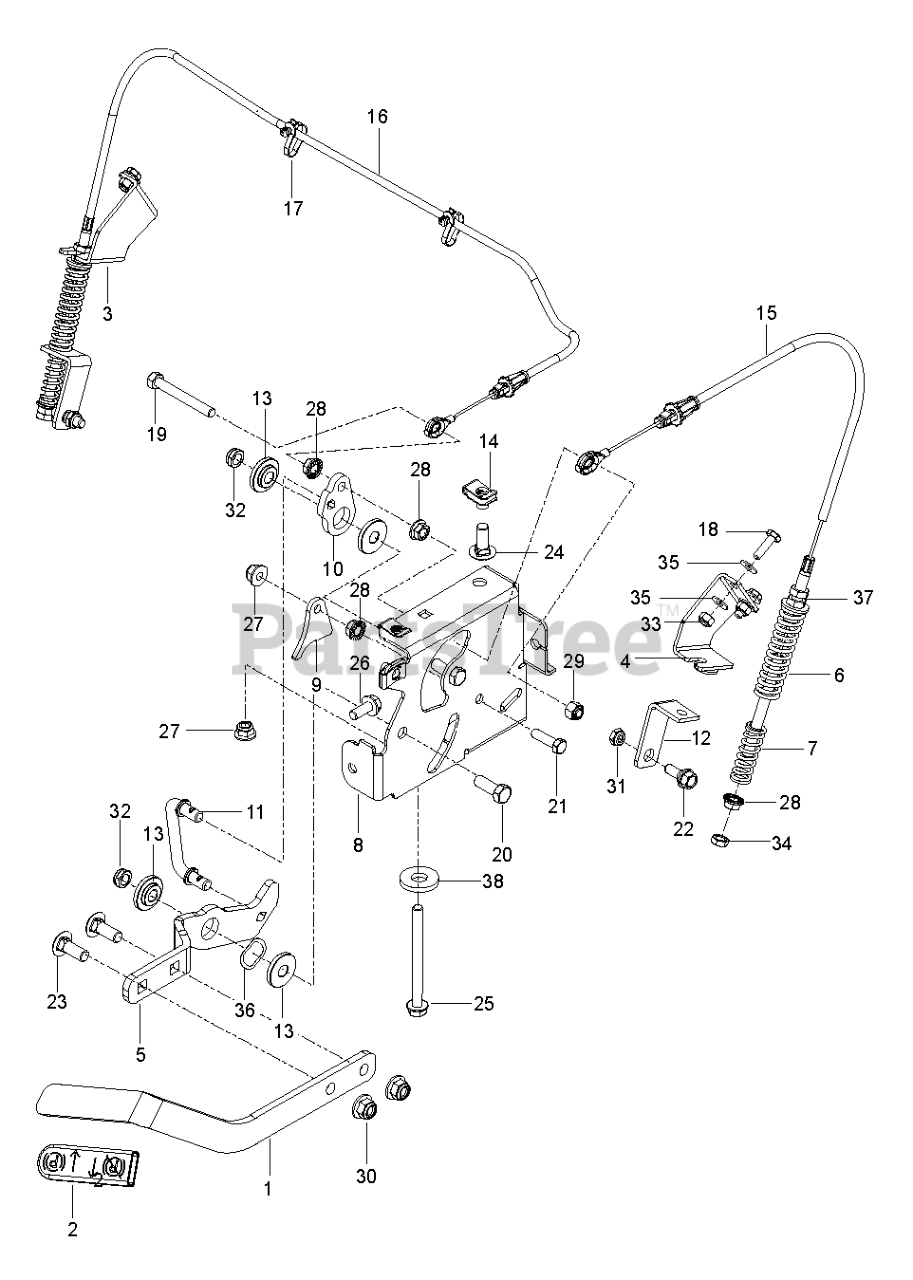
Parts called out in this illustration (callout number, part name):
1	ARM, BRAKE
2	GRIP, PARK BRAKE
3	BRKT, BRAKE RT, BLK
4	BRKT, BRAKE LT, BLK
5	LEVER.PNT.BRAKE.E-DIP
6	SPRING, RETURN
7	SPRING, ENGAGEMENT
8	MOUNT.BRAKET.PNT.BLACK.MS431
9	ACTUATOR, SWITCH
10	BELLCRANK, BRAKE
12	BRKT, BRAKE, BLK
13	BUSHING, BRAKE
14	U-CLIP 5/16-18 NUT RETAINER
15	CABLE.ASSY.BRAKE.CABLE.SHORT
16	CABLE.ASSY.BRAKE.CABLE.LONG
17	TIE WRAP, 8-3/8", W/CLIP
24	GSPW Bolts
27	NUT HEXAGON FLANGE 5/16-18 ST
28	GSPW Hardware
33	NUT HEXAGON 1/4-20 ST ZPB
36	WASHER, .825 X 1.087, WAVE
37	WASHER PLAIN WASHER 3/8 X 0.08
